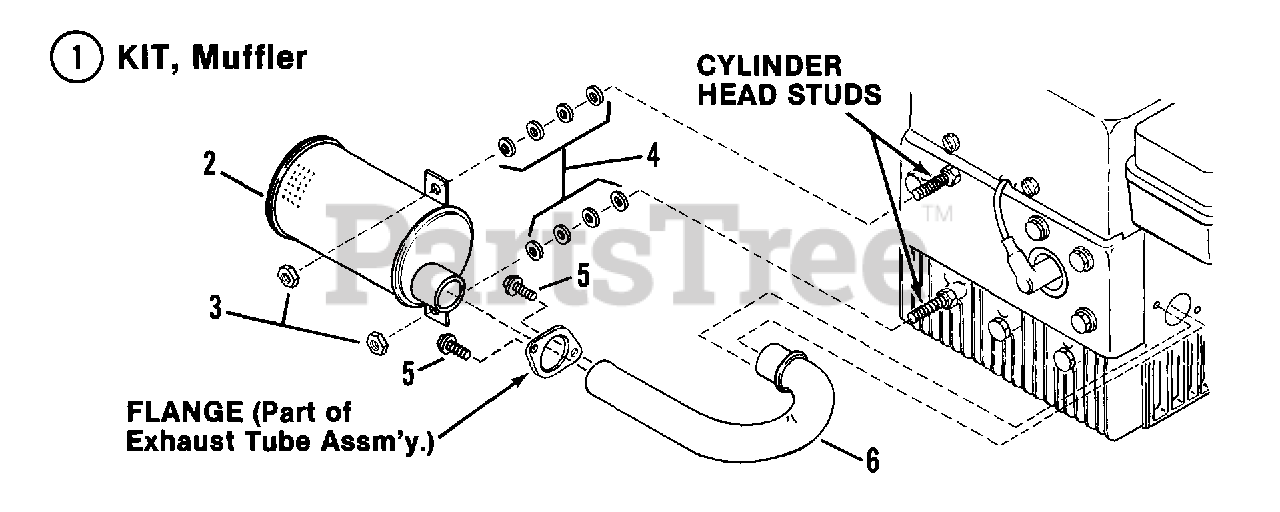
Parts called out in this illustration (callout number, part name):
1	KIT, Muffler
2	MUFFLER
3	NUT, 5/16-18 Hex
4	WASHER, 5/16 SAE
5	CAPSCREW, 5/16Cx3/4" Hex Head
6	TUBE, Exhaust
